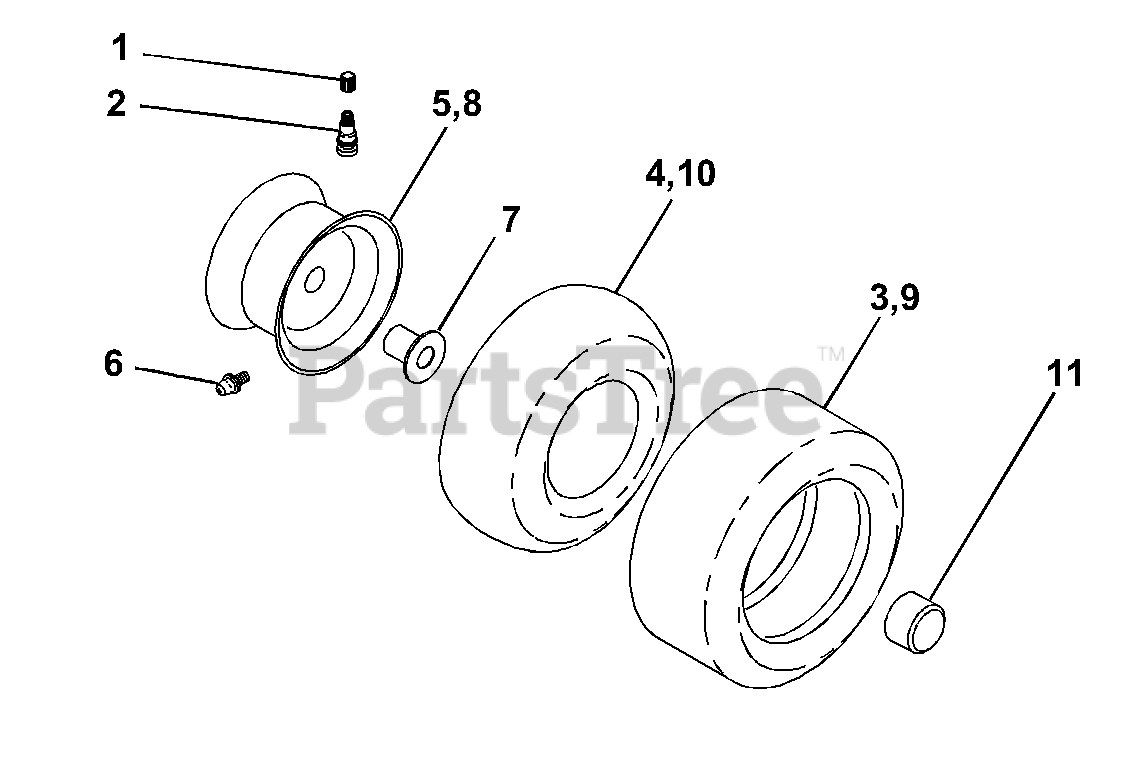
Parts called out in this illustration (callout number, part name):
2	VALVE STEM LT
3	TIRE HEAVY DUTY
4	TUBE.5.3/4.5/6
5	RIM ASM 6" FRONT SILVER
6	FITTING LT
7	BEARING T
8	RIM ASM 8" REAR SILVER
9	TIRE
10	TUBE
11	CAP.HUB.FRONT.LT.BLACK
